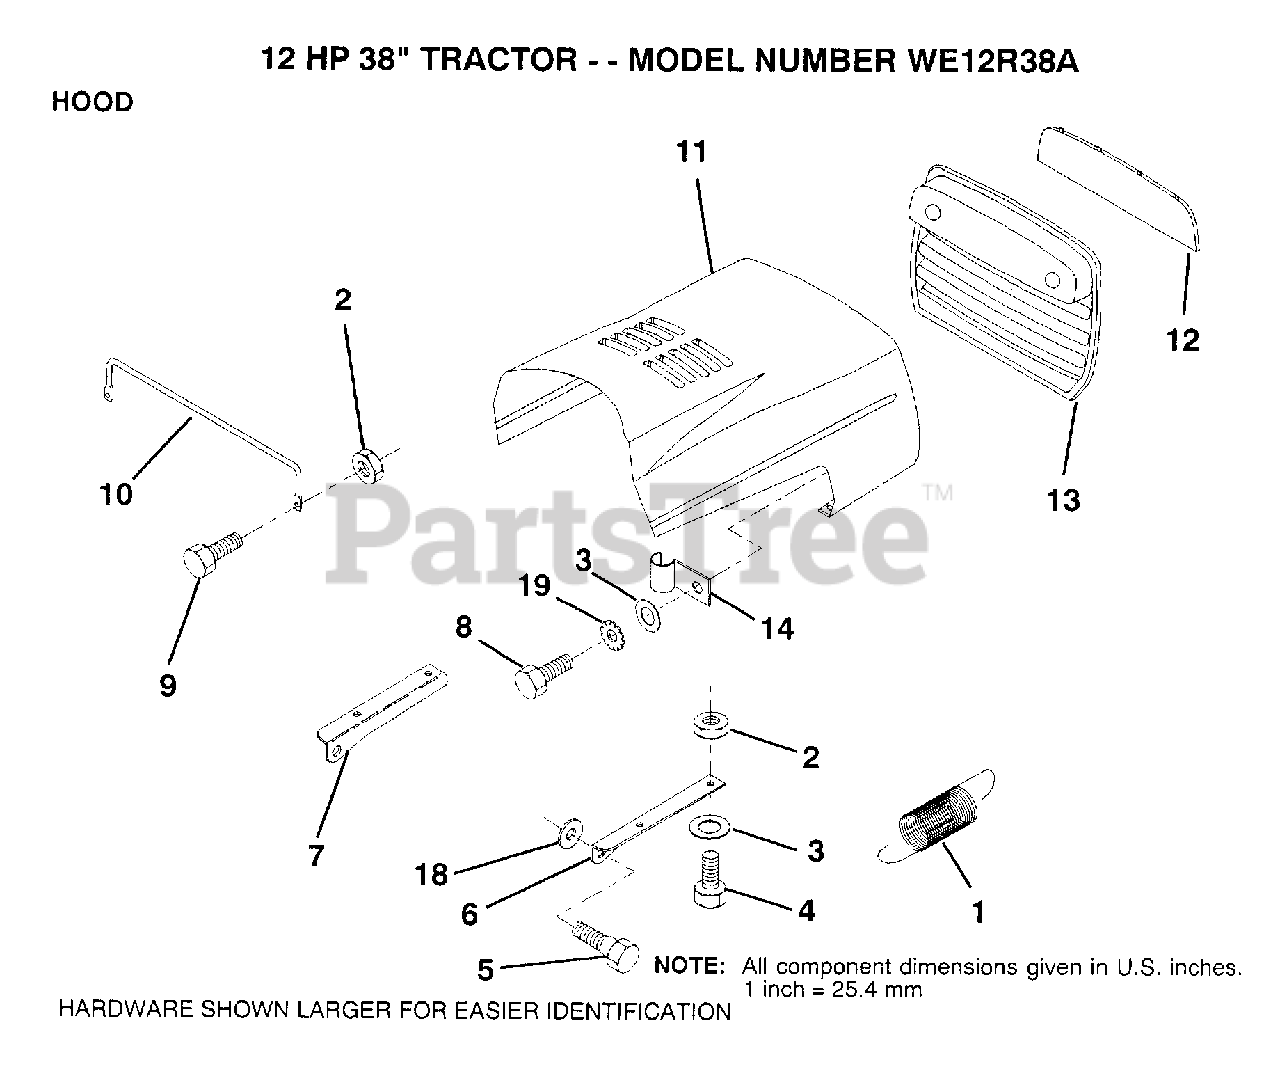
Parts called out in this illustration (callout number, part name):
1	EXT SPRING
2	NUT
3	WASHER
4	BOLT
6	BRKT HOOD RH
7	BRKT HOOD LH
10	"BRACE,HOOD"
11	HOOD
12	LENS
13	GRILL
14	CLIP T
18	WASHER
19	LOCKWASHER GT
